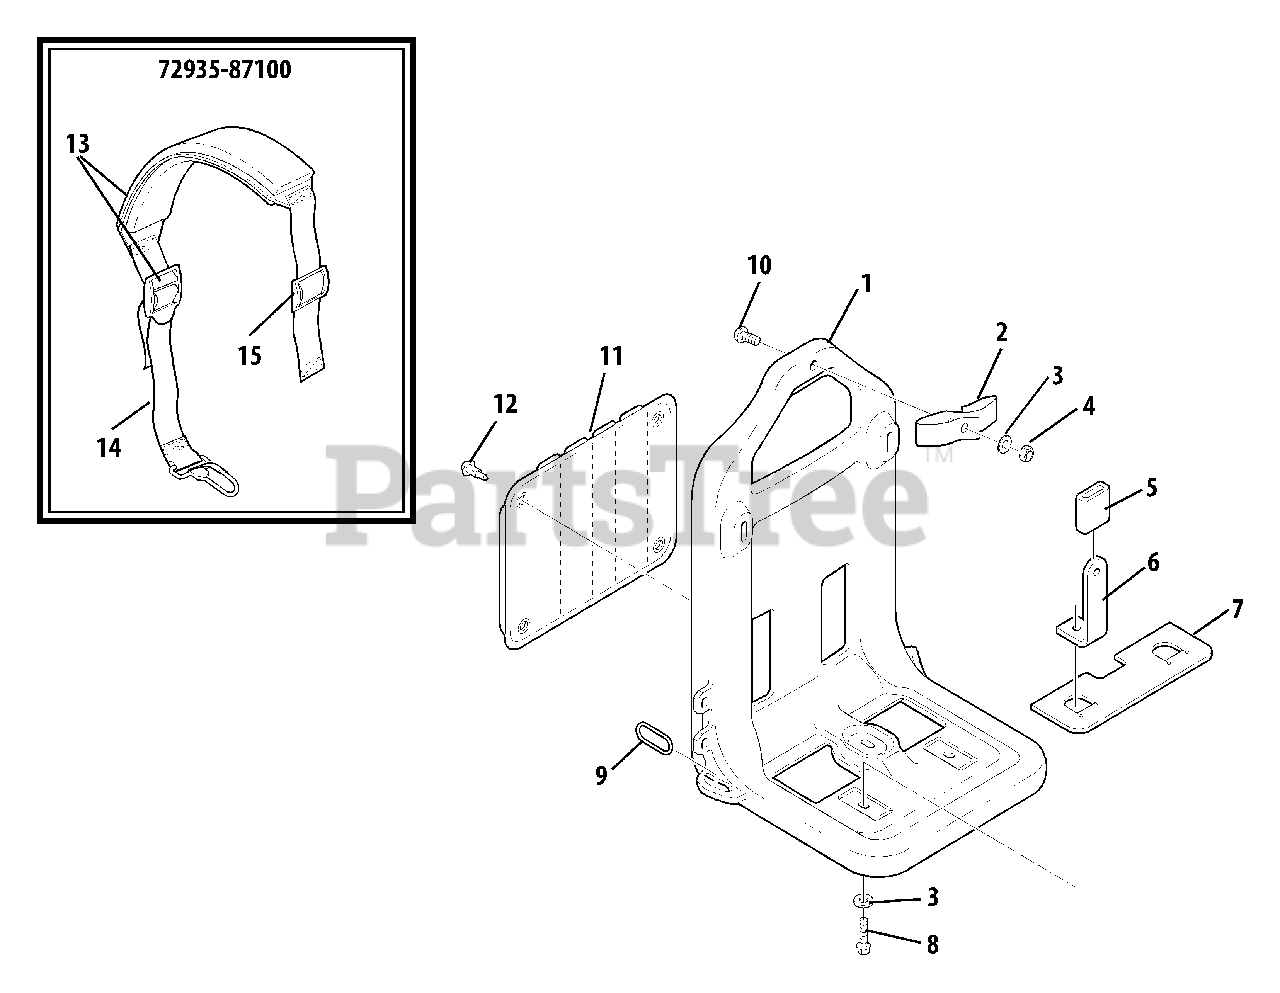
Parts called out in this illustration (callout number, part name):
1	FRAME, BACKPACK
2	HANGER, HARNESS
3	COLLAR Ø18ר6.4×L2
4	NUT, LOCK M6
5	CUSHION
6	BRACKET
7	CUSHION
8	BOLT M6×20
9	RING, HARNESS
10	SCREW, TRUSS M6×30
11	PAD, BACKPACK
12	CLIP
13	HARNESS
14	STRAP, HARNESS
15	BUCKLE
72935-87100	HARNESS ASSY
